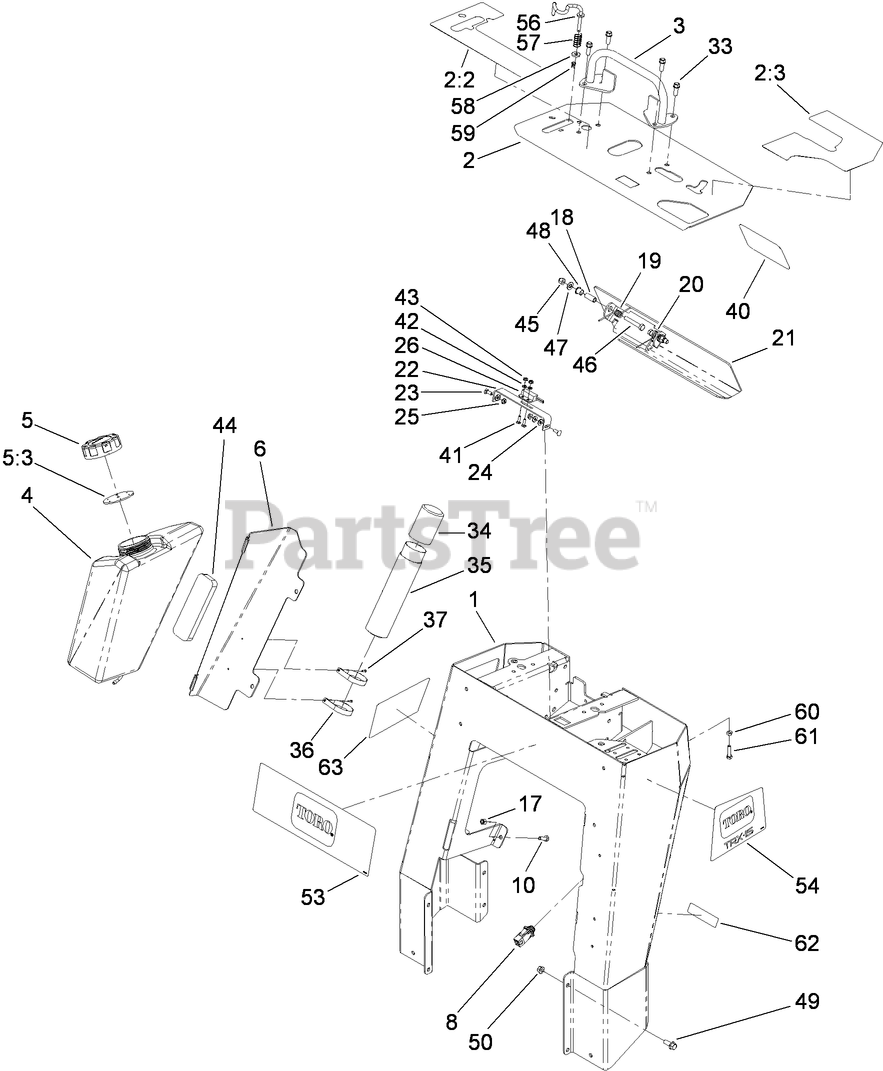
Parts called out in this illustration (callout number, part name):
2	PANEL-CONTROL
2:2	DECAL-CONSOLE, RH
2:3	DECAL-CONSOLE, LH
3	BAR-REFERENCE
4	TANK-FUEL
5	CAP-FUEL, GAS
5:3	GASKET-VENTED
6	BRACKET-COVER, TANK
8	SWITCH-PLUNGER
10	SCREW-HH
17	NUT-LOCK, NI
18	SPACER-SPRING
19	SPRING-TORSION, LH
20	SPRING-TORSION, RH
21	PLATE-REVERSE
22	PLATE-SWITCH
23	BOLT-CARR
24	WASHER-FLAT
25	NUT-KEPS
26	SWITCH-PROXIMITY
33	SCREW-TAPTITE
34	CAP-HOUSING
35	TUBE-MANUAL
36	CLAMP-R
37	RIVET-POP
41	SCREW-CARR
42	WASHER-FLAT
43	NUT-KEPS
44	PAD-FOAM
45	NUT-LOCK, NI
46	SCREW-HH
47	WASHER-FLAT
48	BUSHING-NYLINER
49	SCREW-HHF
50	NUT-FLANGE
56	ROD-INTERLOCK
57	SPRING-CONTROL
58	WASHER-FLAT
59	PIN-COTTER
60	SCREW-HH
61	NUT-JAM
62	DECAL-ARRESTER, SPARK
63	DECAL-SIDE, RH
